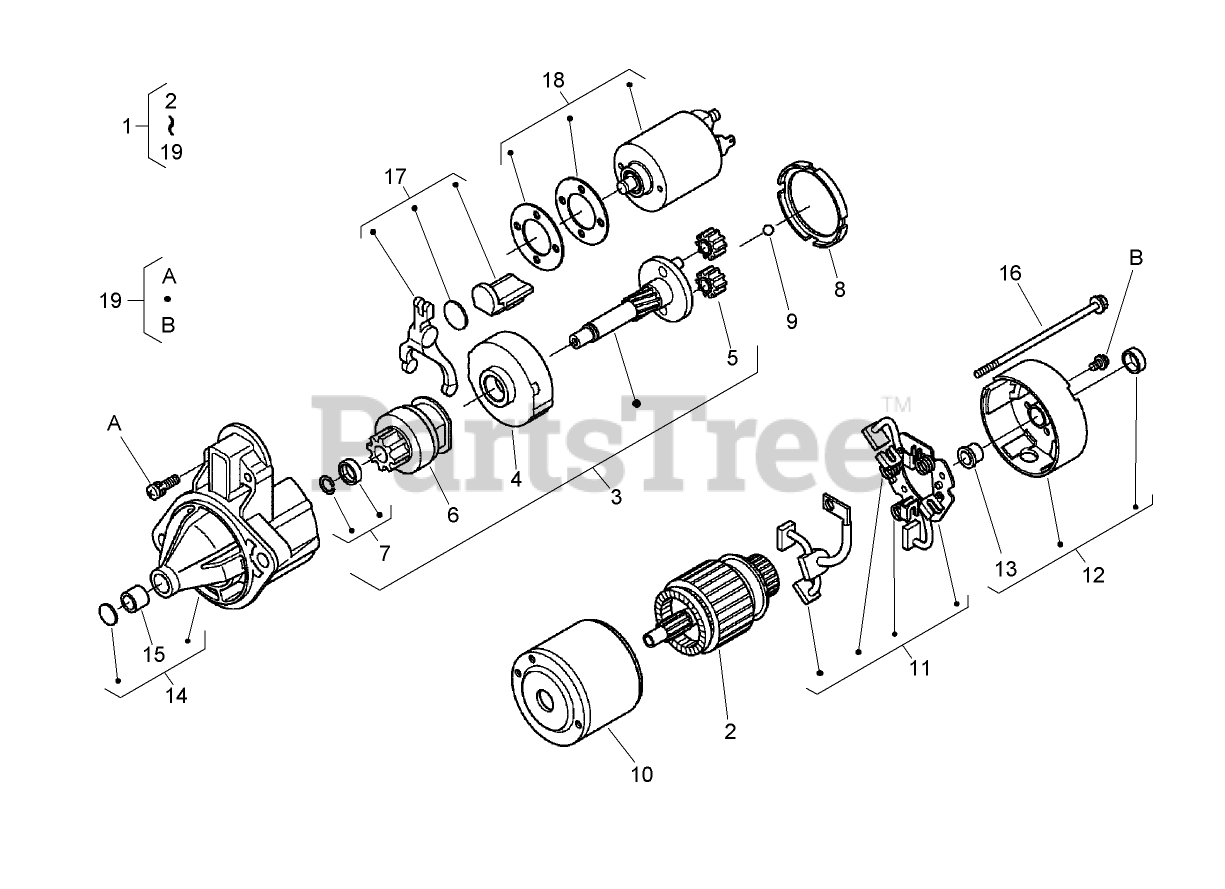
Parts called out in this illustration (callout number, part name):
1	STARTER ASM
2	ARMATURE
3	SHAFT ASM
4	GEAR-INTERNAL
5	GEAR-PLANETARY
6	CLUTCH-RUNNING, OVER
7	STOPPER
8	GASKET
11	BRUSH HOLDER ASM
12	REAR BRACKET ASM
13	BUSHING
14	FRONT BRACKET ASM
15	BUSHING
17	FORK LEVER ASM
18	MAGNETIC SWITCH ASM
19	SCREWS (SET OF 4)
